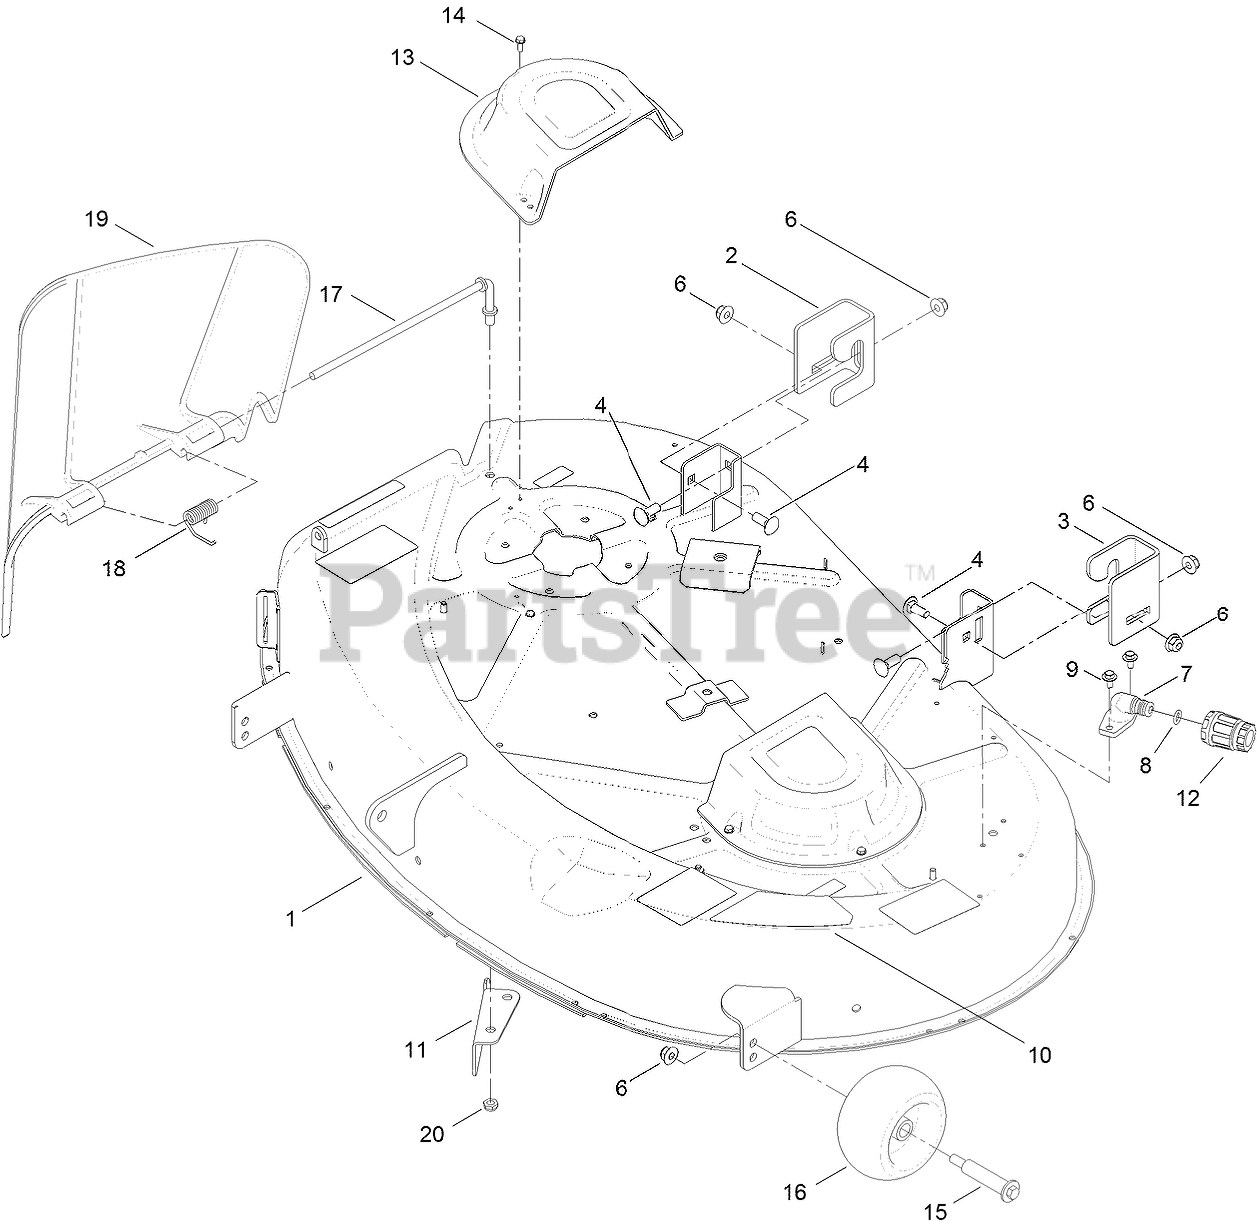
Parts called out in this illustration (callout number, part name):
1	42 INCH DECK AND DECAL ASM
2	BRACKET-HANGER, RH
3	BRACKET-HANGER, LH
4	BOLT-CARR
6	NUT-HF, NI
7	FITTING-WASHOUT
8	O-RING
9	SCREW-HHFTF
11	BAFFLE-CUTOFF
12	CONNECTOR-HOSE
13	COVER-BELT
14	SCREW-TAPTITE
15	BOLT-SHOULDER
16	ROLLER-SCALP, ANTI
17	ROD-PIVOT
18	SPRING-TORSION
19	DEFLECTOR
20	NUT-LOCK, NI
